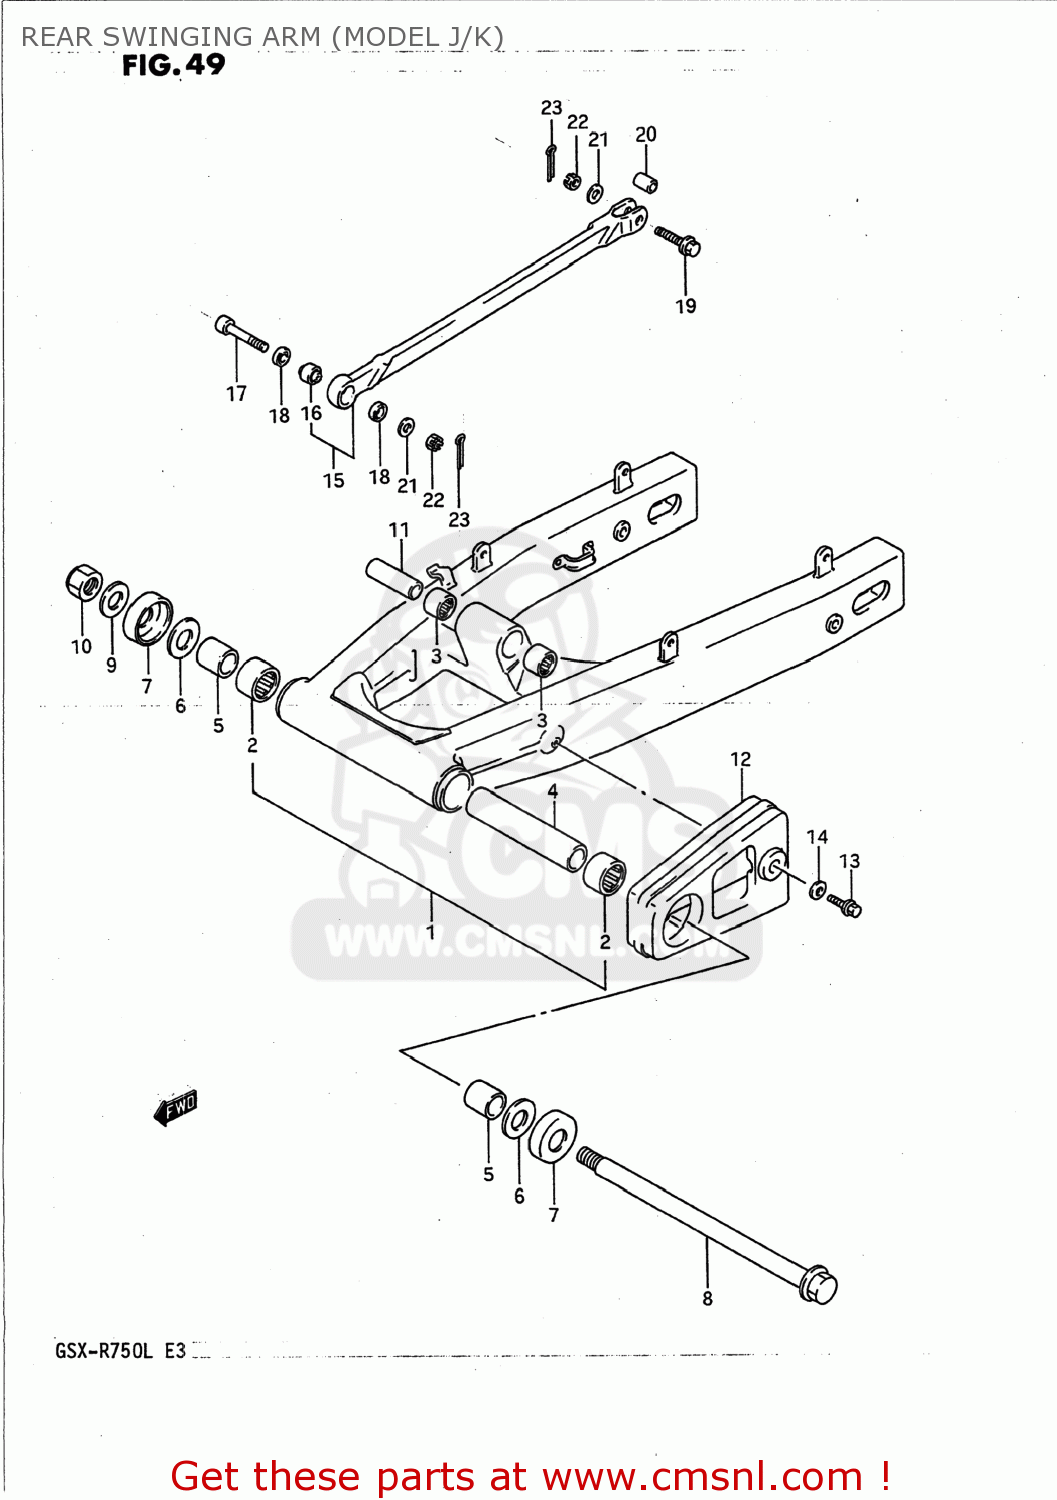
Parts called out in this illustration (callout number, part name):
1	SWING ARM ASSEMBLY,REAR
2	BEARING(25X33X30)
3	BEARING(20X27X23.5)
4	SPACER,RR SWGARM PIVOT CTR
5	SPACER,RR SWGARM PIVOT BERRING
6	WASHER
7	DUST SEAL,RR SWGARM PIVOT
8	SHAFT,REAR SWING ARM PIVOT
9	WASHER
10	NUT
11	SPACER,RR CUSHION LEVER
12	BUFFER,CHAIN TOUCH DEFENCE
13	BOLT
14	WASHER
15	TORQUE LINK SET,REAR
16	SPHERICAL BEARING,TORQUE
17	BOLT(8X48)
18	19
19	BOLT
20	SPACER,RR TORQUE LINK RR
21	WASHER
22	NUT 8MM
23	PIN 20X20
